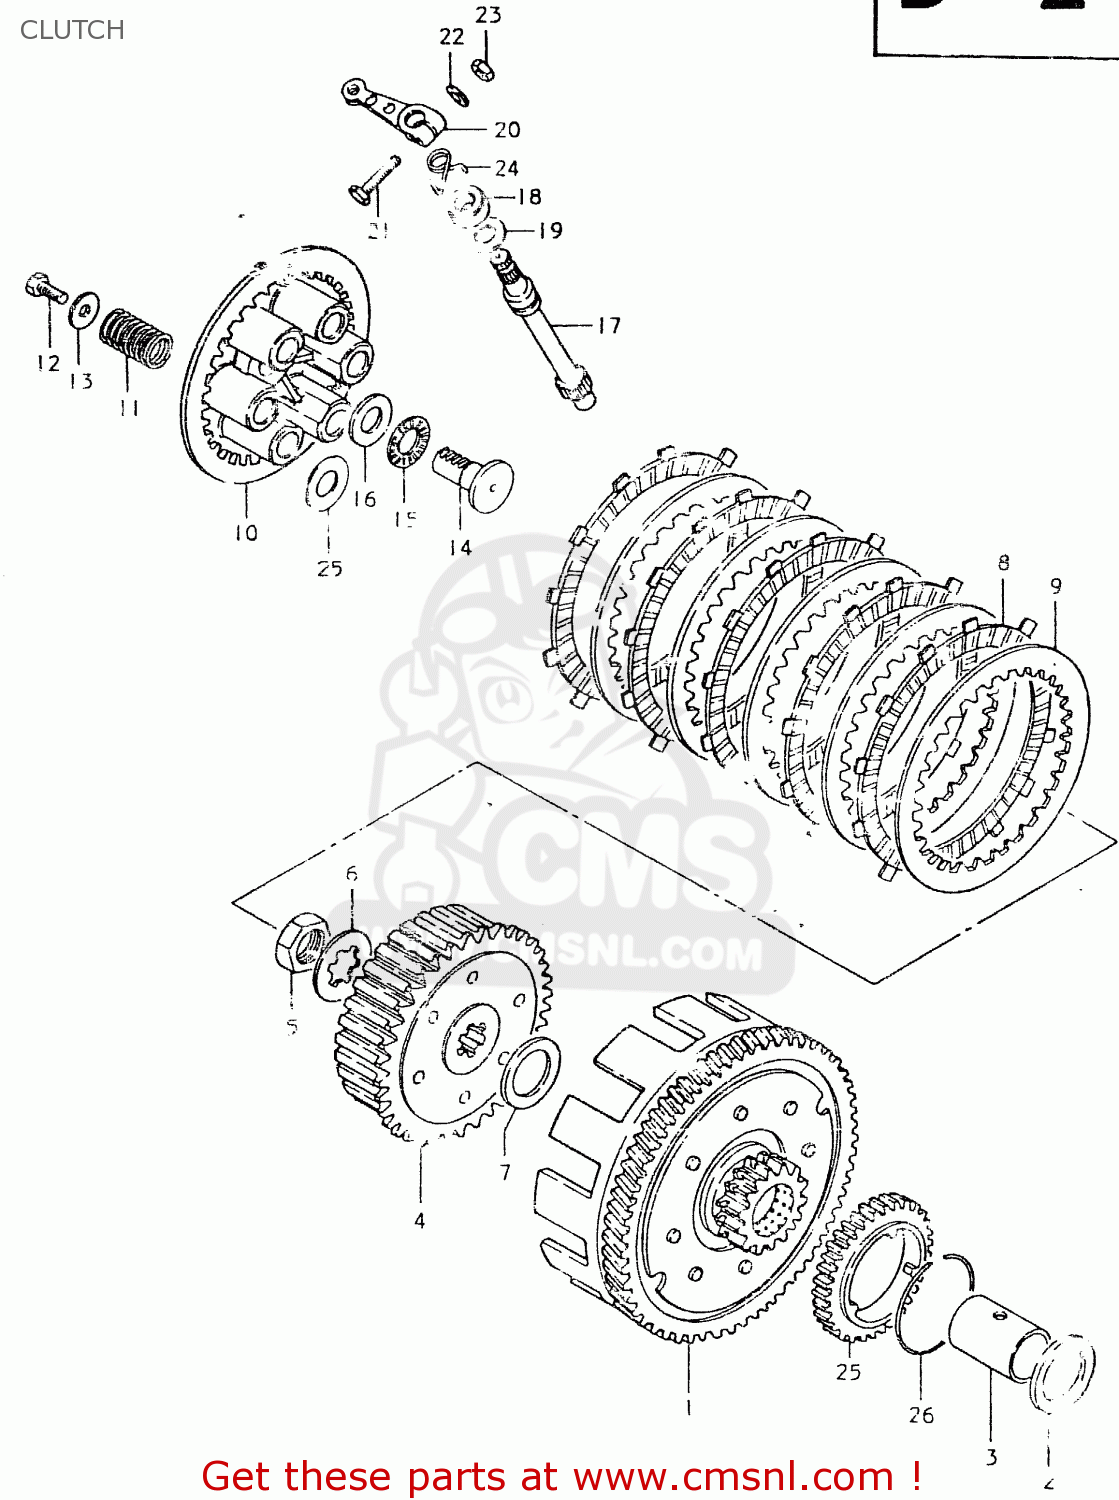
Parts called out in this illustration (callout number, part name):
1	GEAR ASSEMBLY,PRIMARY DRIVE
2	WASHER
3	SPACER
4	HUB,CLUTCH SLEEVE
5	NUT (20MM)
6	WASHER,LOCK
7	WASHER(20X38X2)
8	PLATE,CLUTCH DRIVE (MCA)
9	PLATE,CLUTCH DRIVEN (NAS)
10	DISC,CLUTCH PRESSURE
11	SPRING
12	BOLT, UPPER
13	WASHER
14	RACK,CLUTCH RELEASE
15	BEARING(15X28X2)
16	WASHER
17	PINION,CLUTCH RELEASE
18	OIL SEAL
19	WASHER (14.2X22X1)
20	ARM,CLUTCH RELEASE
21	BOLT,REAR
22	SPRING
23	GEAR,OIL PUMP DRIVE
24	CIRCLIP
25	WASHER
